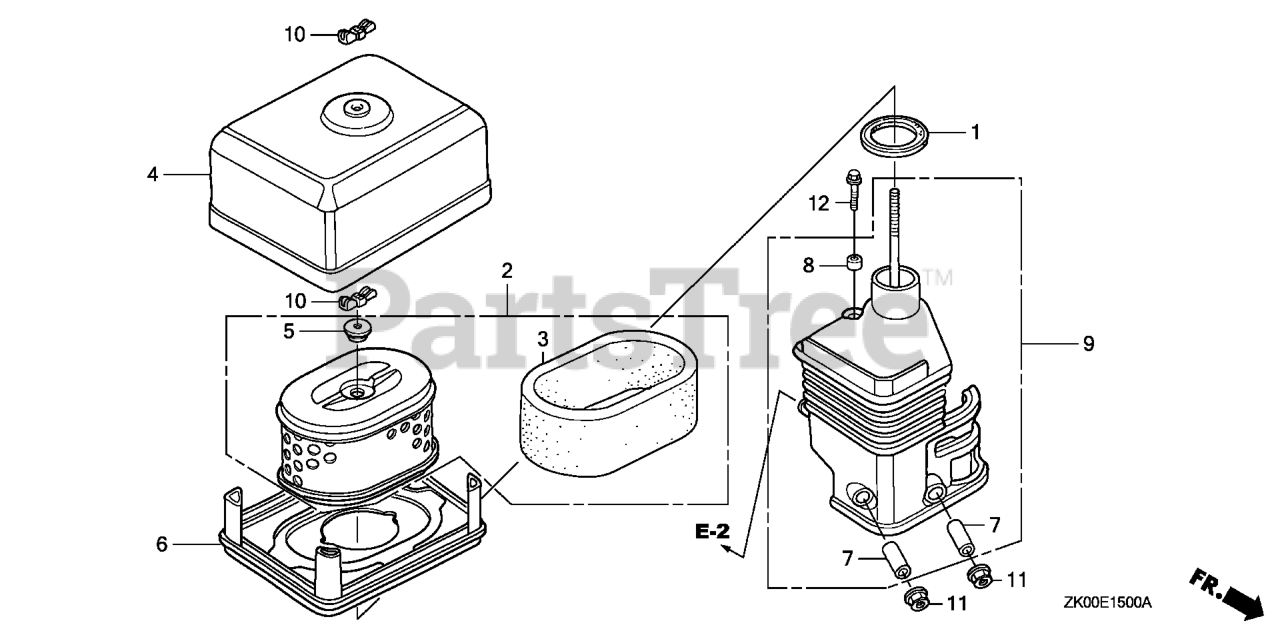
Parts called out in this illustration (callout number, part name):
1	GASKET, ELBOW
2	ELEMENT, AIR CLEANER (DUAL) Use up to Engine SN 2115700.
2	ELEMENT, AIR CLEANER (DUAL)
3	FILTER (OUTER)
4	COVER, AIR CLEANER (DUAL)
5	GROMMET, AIR CLEANER
6	NOSE, MUFFLER
7	COLLAR, AIR CLEANER Use from Engine SN 1786085.
8	COLLAR B, AIR CLEANER
9	ELBOW, AIR CLEANER
10	WINGNUT, TOOL BOX SETTING
11	NUT, FLANGE (6MM)
12	BOLT, FLANGE (6X20)
